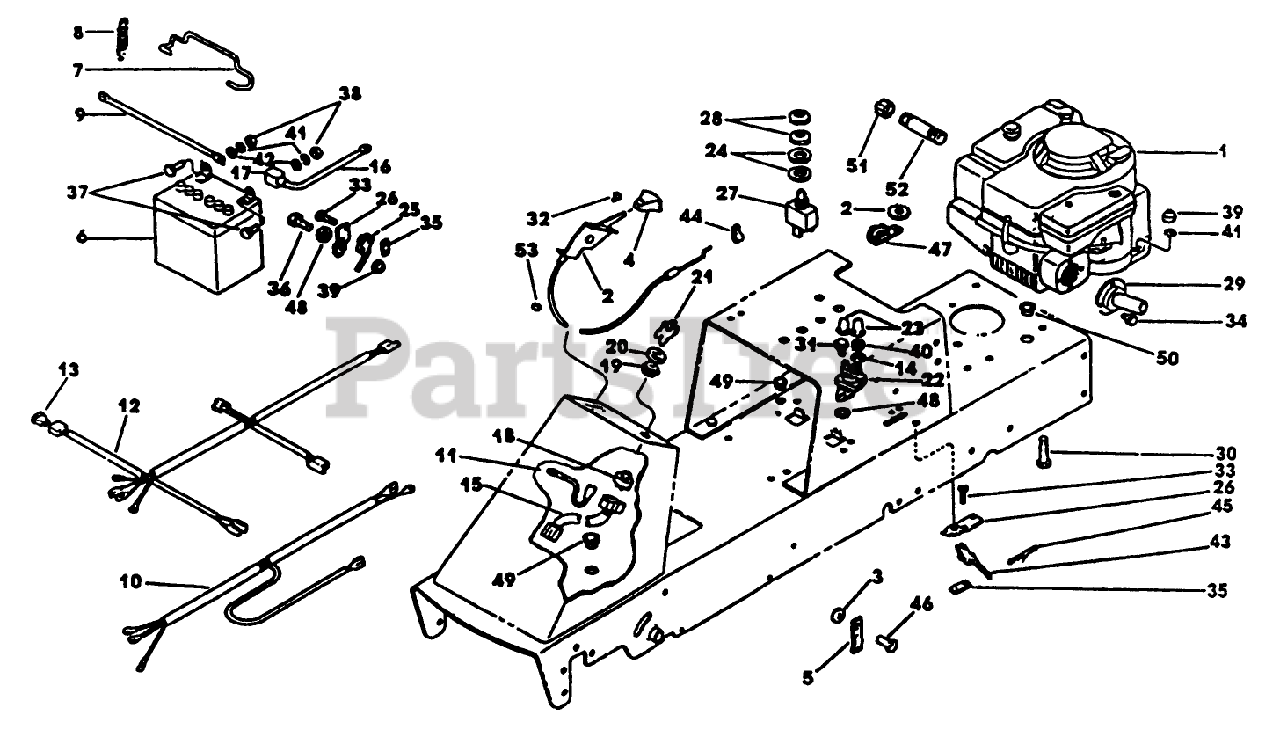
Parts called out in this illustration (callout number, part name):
4	THROTTLE KNOB
7	ROD - BATTERY
8	SPRING
9	CABLE - GROUND
10	WIRING HARNESS
11	WIRE ASSEMBLY
16	CABLE AY - POS.
19	NUT
20	BEZEL
21	KEY
22	SOLENOID
26	BRACKET, SWITCH
27	SEAT INTERLOCK SWITCH
31	SCREW-THREAD FRMG
32	SCREW - PPH
37	SCREW - HEX
38	NUT SS
39	NUT
40	NUT-HEX
43	SWITCH-SEALED
47	CLAMP - J EX
50	BUSHING
